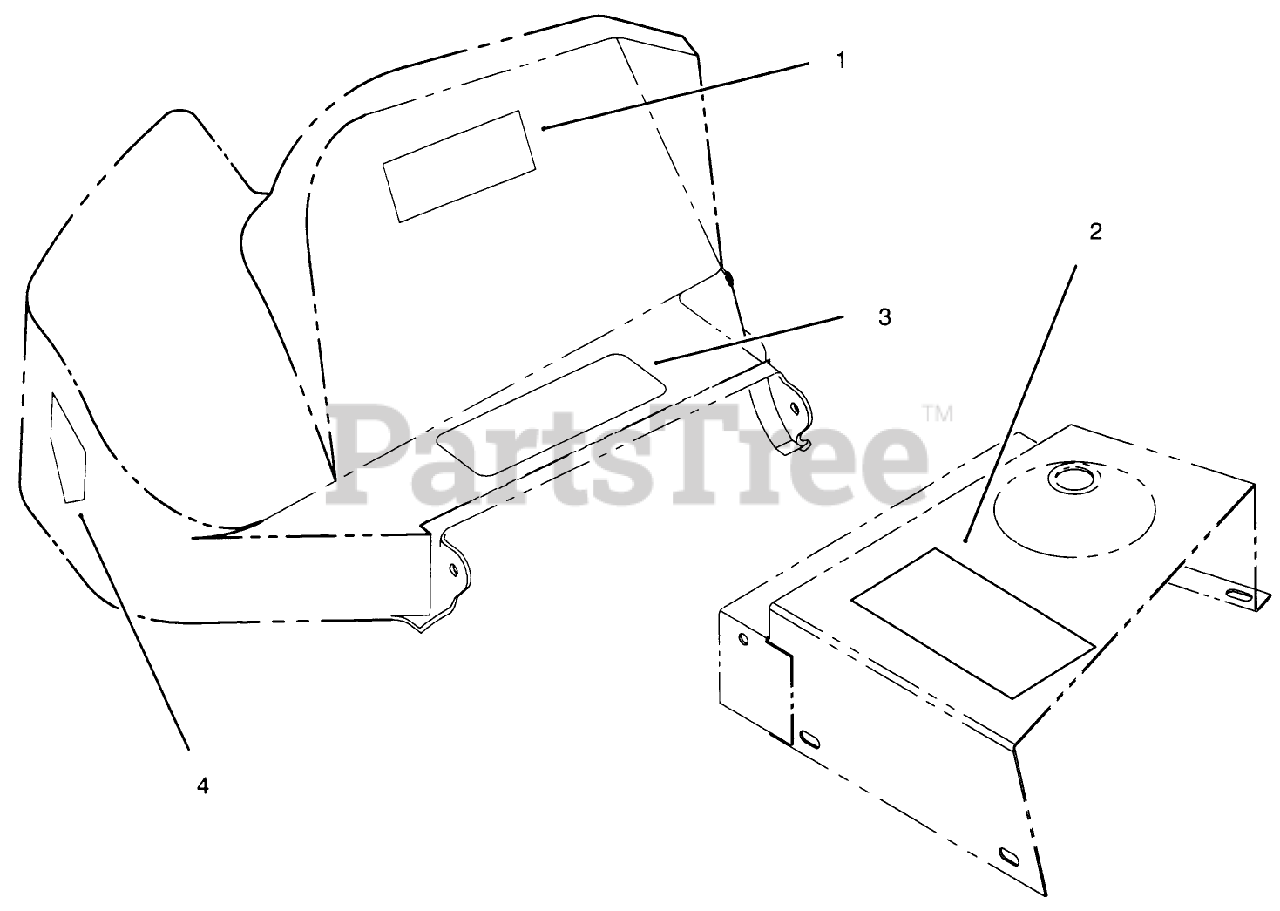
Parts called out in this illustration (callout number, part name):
1	DECAL - WARNING
2	DECAL-DANGER
3	DECAL-DANGER
4	DECAL-DANGER
